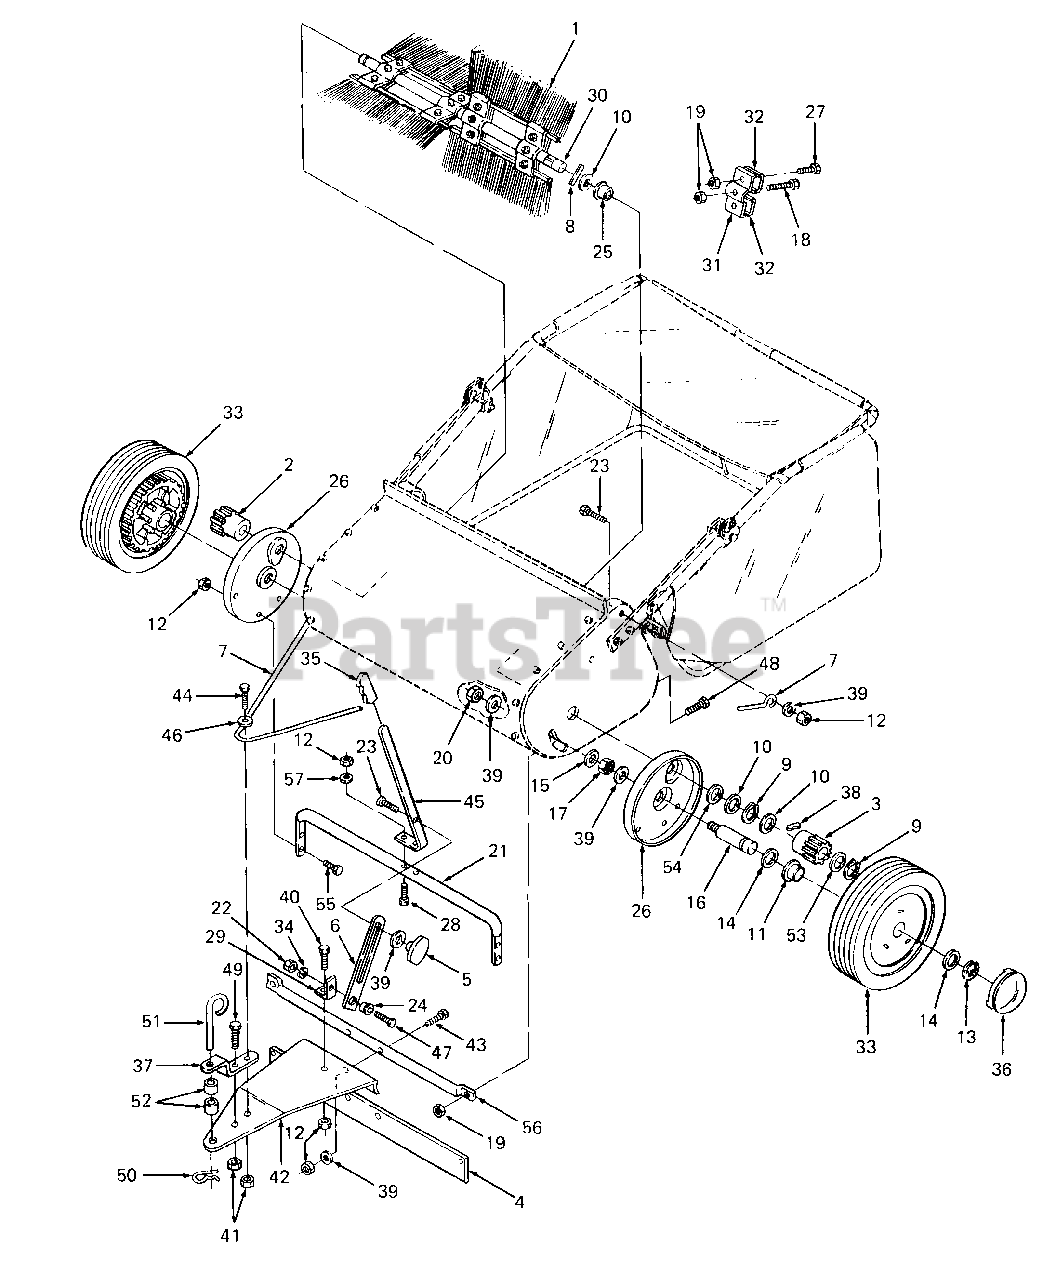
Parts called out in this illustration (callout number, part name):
2	Gear, Pinion RH
3	Gear, Pinion LH
5	Knob, Height Adjustment
6	Strap, Height Adjustment
7	Rod, Brace
8	Pin, Spring, 3/16 X 1
9	Ring, Retaining, .594 ID
10	Washer, Flat, .596 X 1.125 X.025
11	Bearing, Flange
12	Nut, Hex Lock, 5/16-1 8 Thd
13	E-Ring, 5/8
14	Washer, Flat, .62 ID X 1.00 OD
15	Washer, Flat, 3/8 ID X 1 OD
17	Nut, Jam, 3/8-24 Thd
18	Bolt, Hex, 1/4-20 X 1 Lg
19	Nut, Hex Lock, 1/4-20 Thd
20	Nut, Hex Lock, 3/8-24 Thd
21	Tube, Height Adjustment
22	Nut, Hex, 5/16-18 Thd
23	Bolt, Carriage, 5/16-18 X 3/4 Lg
24	Spacer, Bushing
25	Bushing, Brush Shaft
26	Cover, Dust
27	Bolt, Hex, 1/4-20 X.75 Lg GR5
28	Bolt, Curved Hd, 5/16-18 X 1-5/8
29	Bracket, Angle
30	Shaft, Brush 1
31	Retainer, Brush (Double)
32	Retainer, Brush (Single)
33	Wheel Assy, Complete
34	Washer, Lock, 5/16 ID
36	Hub Cap
38	Pawl (H.T.)
39	Washer, Flat, 5/16 Std
40	Bolt, Hex, 5/16-1 8 X 3/4 Lg
41	Nut, Hex Lock, 3/8-16 Thd
42	Tongue, Hitch 1
43	Bolt, Carriage, 5/16-18 X 1-1/2
44	Bolt, Hex, 3/8-16 X 1.5 Lg
45	Handle, Height Adjustment
46	Washer, Flat, 17/32 X 1-1/2
47	Bolt, Truss Hd, Slotted, 5/16-18 X 3/4 ..
48	Bolt, Carriage, 1/4-20 X 5/8
49	Bolt, Hex, 3/8-16 X 3/4 Lg GR5
50	Cotter, Hairpin, 5/32
51	Pin, Hitch
52	Tube, Hitch Adjustment
53	Washer, Flat, .596 X .859 X .025
54	Washer, Flat, .78 ID
55	Bolt, Hex, 5/16-18 X 1/2 Lg
56	Tube, Hitch
57	Washer, Bowed
